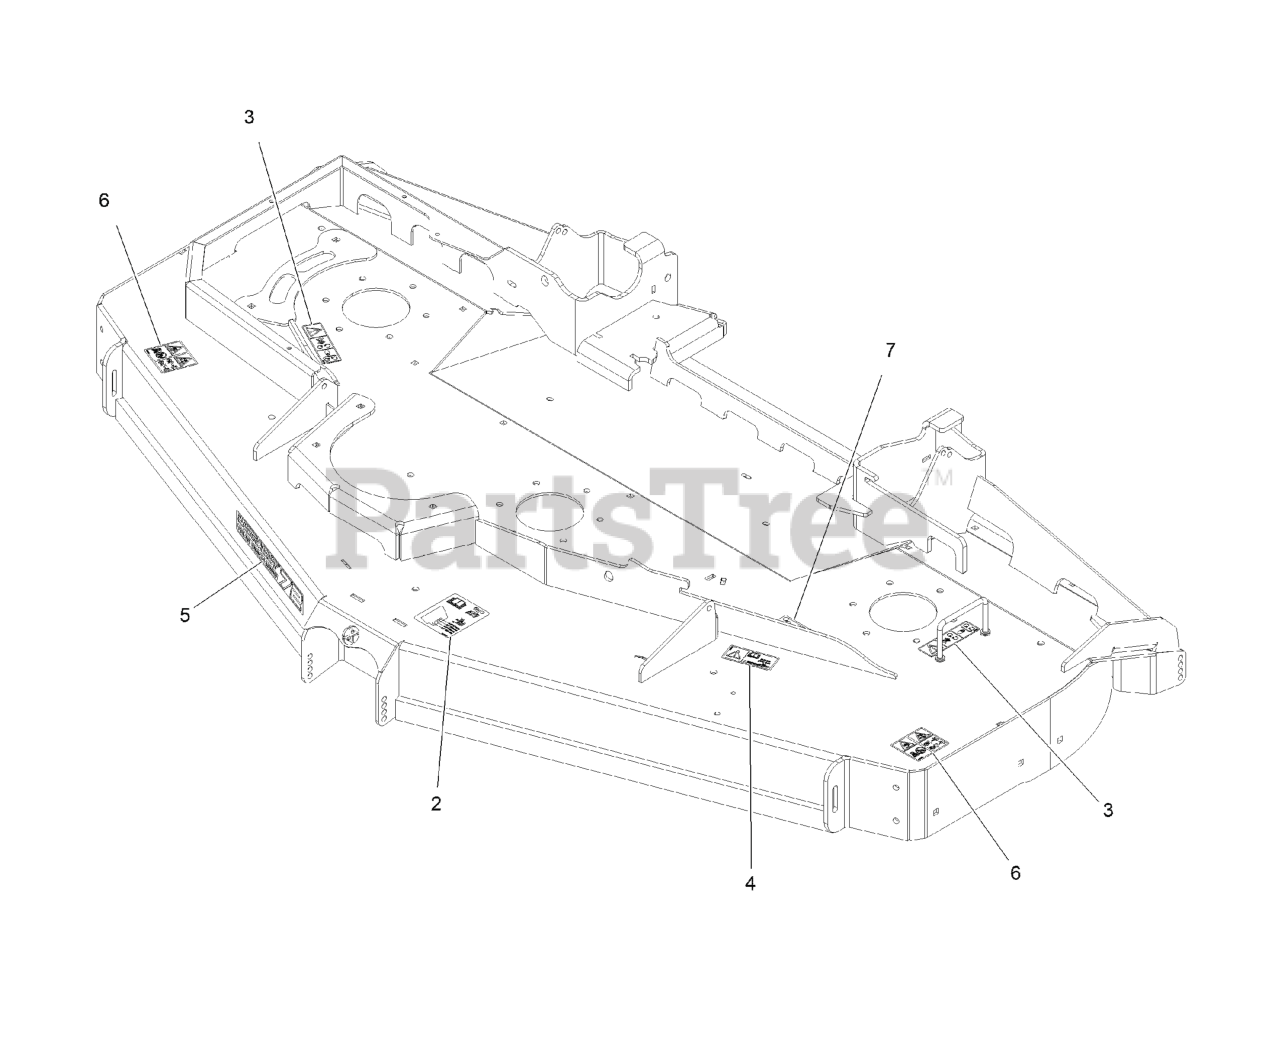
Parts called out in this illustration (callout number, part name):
2	DECAL-ROLLER, ANTI-SCALP
3	DECAL-COVER, MISSING
4	DECAL-TORQUE, BOLT
5	Decal, 72Rd
6	DECAL-DANGER, THROWN OBJECT
7	DECAL-BELT ROUTING REAR
